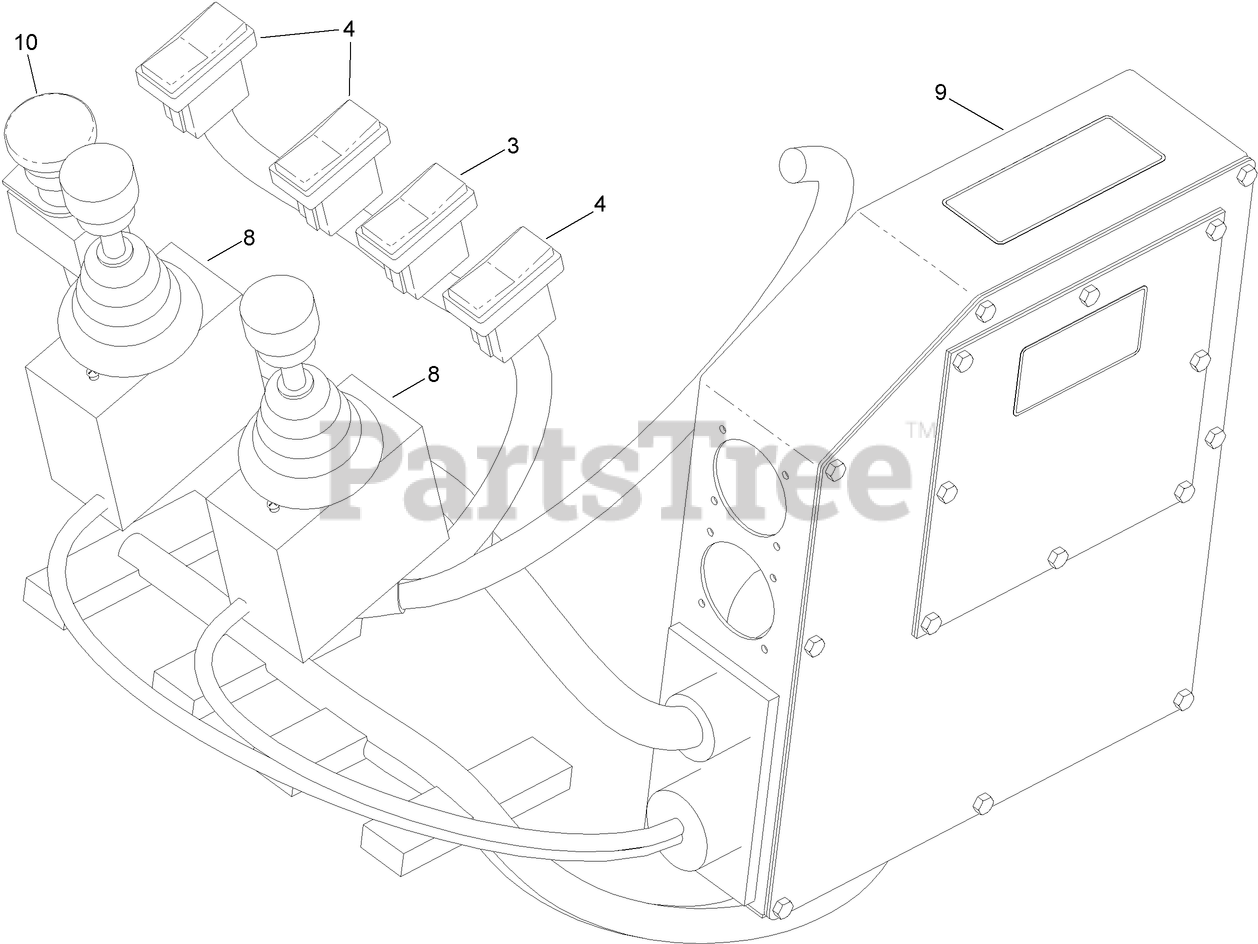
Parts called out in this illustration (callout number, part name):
3	SWITCH-ROCKER, 3 POSITION
4	SWITCH-ROCKER, 2 POSITION
8	CONTROLLER-JOYSTICK
9	BOX-JUNCTION, ELECTRIC
10	CABLE VALVE ASM
